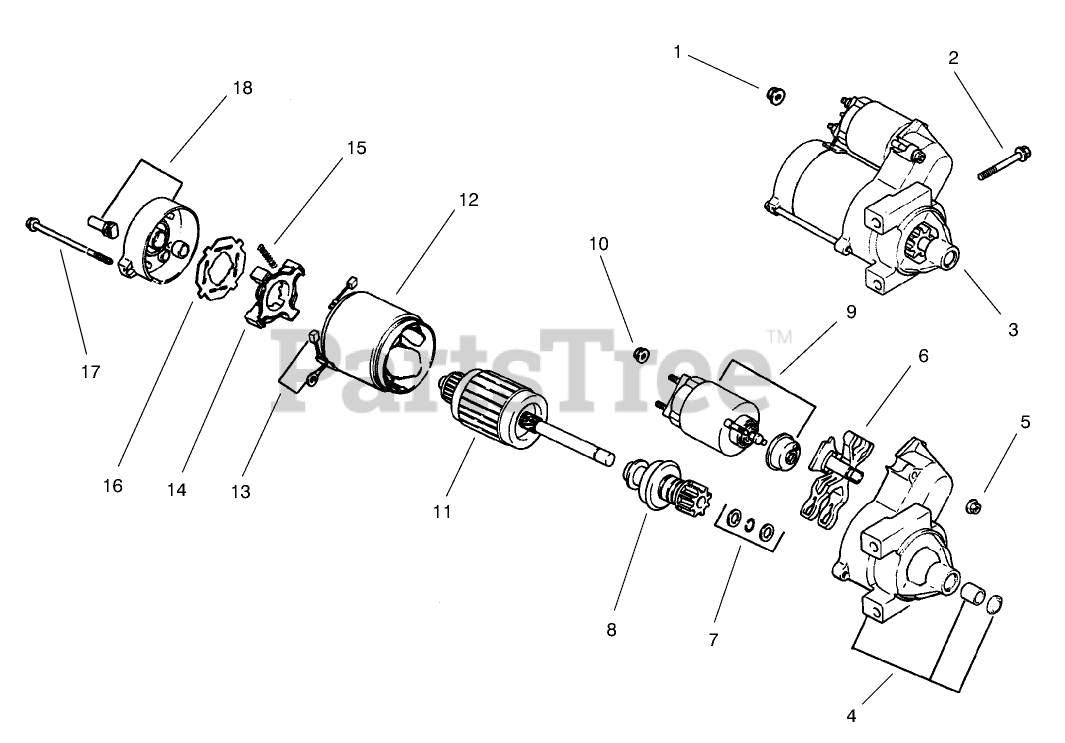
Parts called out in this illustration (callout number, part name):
1	Nut
2	Screw M8x1.25x80 (Only On: 72103, 72083)
3	Starter-Solenoid Shift (Incl. Ref. #4-20)
4	Cap-Drive End
5	Nut Starter
6	Lever Starter Drive
7	Washer
8	Drive-Pinion
9	Solenoid
10	Nut
11	Armature-Starter
12	Frame
13	Kit-Brush (Incl. Ref. # 16)
14	Holder-Brush
15	Spring-Brush
16	Insulator
17	Bolt
18	Commutator-End Cap
